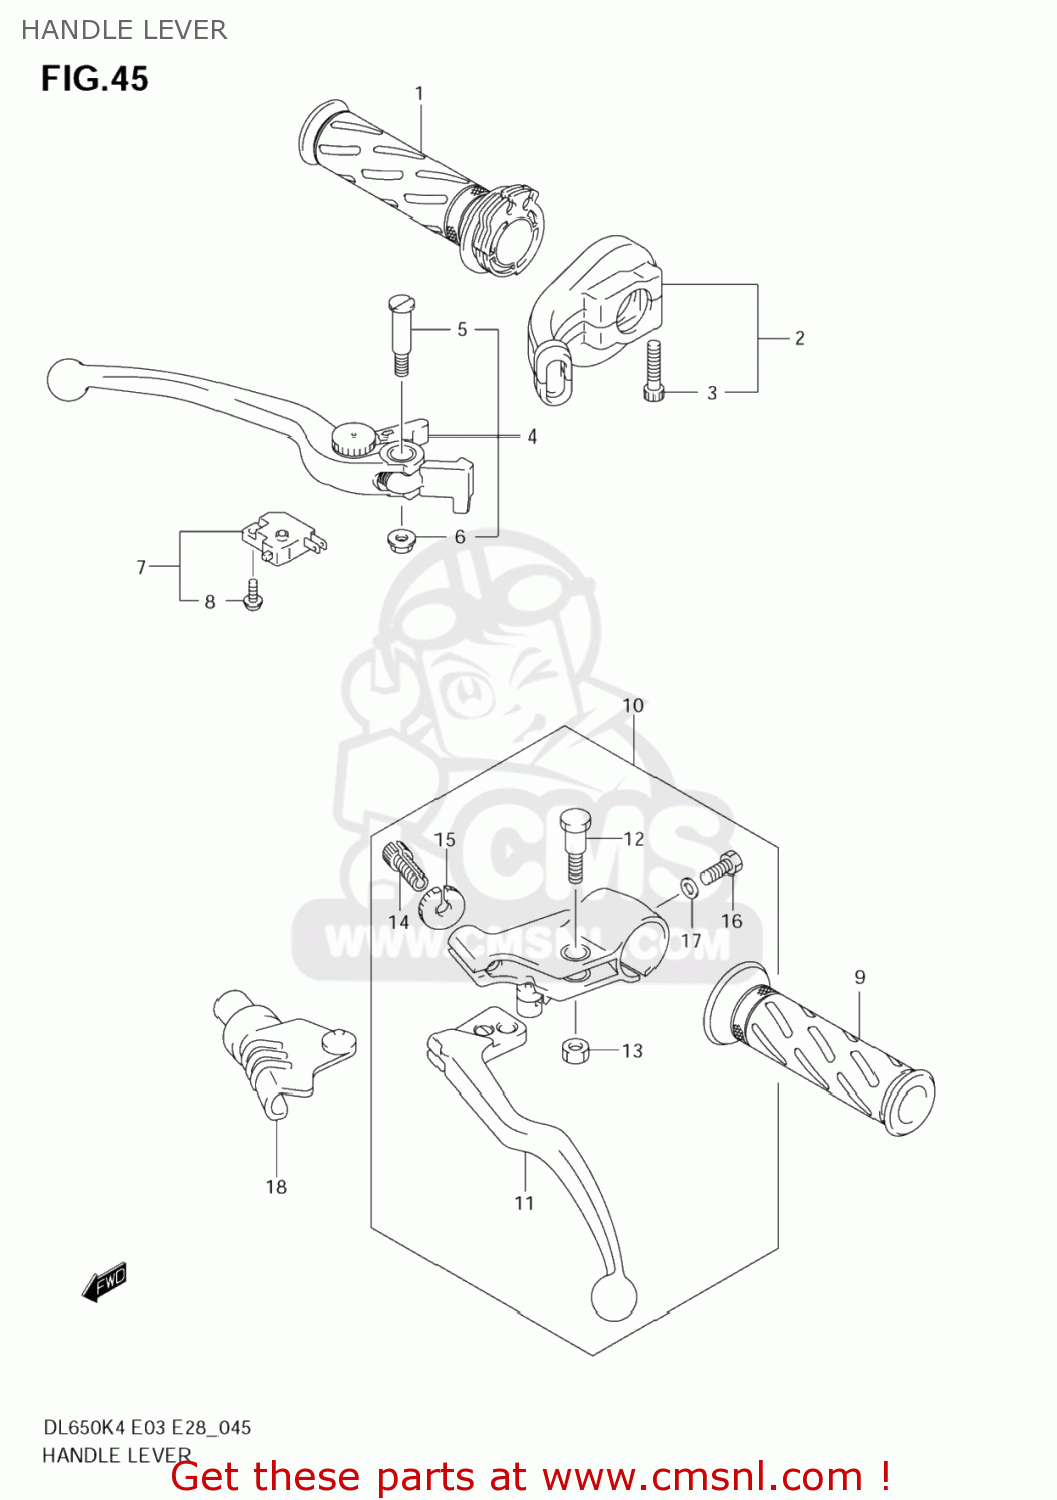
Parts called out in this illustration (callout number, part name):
1	GRIP,THROTTLE
2	CASE ASSY,THROTTLE
3	BOLT
4	LEVER ASSY,BRAKE
5	BOLT,LEVER PIVOT
6	NUT
7	SWITCH ASSY,ST
8	SCREW
9	GRIP,LEFT
10	LEVER ASSY,CLUTCH
11	LEVER,CLUTCH
12	BOLT,LEVER SET
13	NUT
14	ADJUSTER,CABLE
15	NUT,CABLE ADJUSTER
16	BOLT
17	WASHER
18	COVER,CLUTCH LEVER
